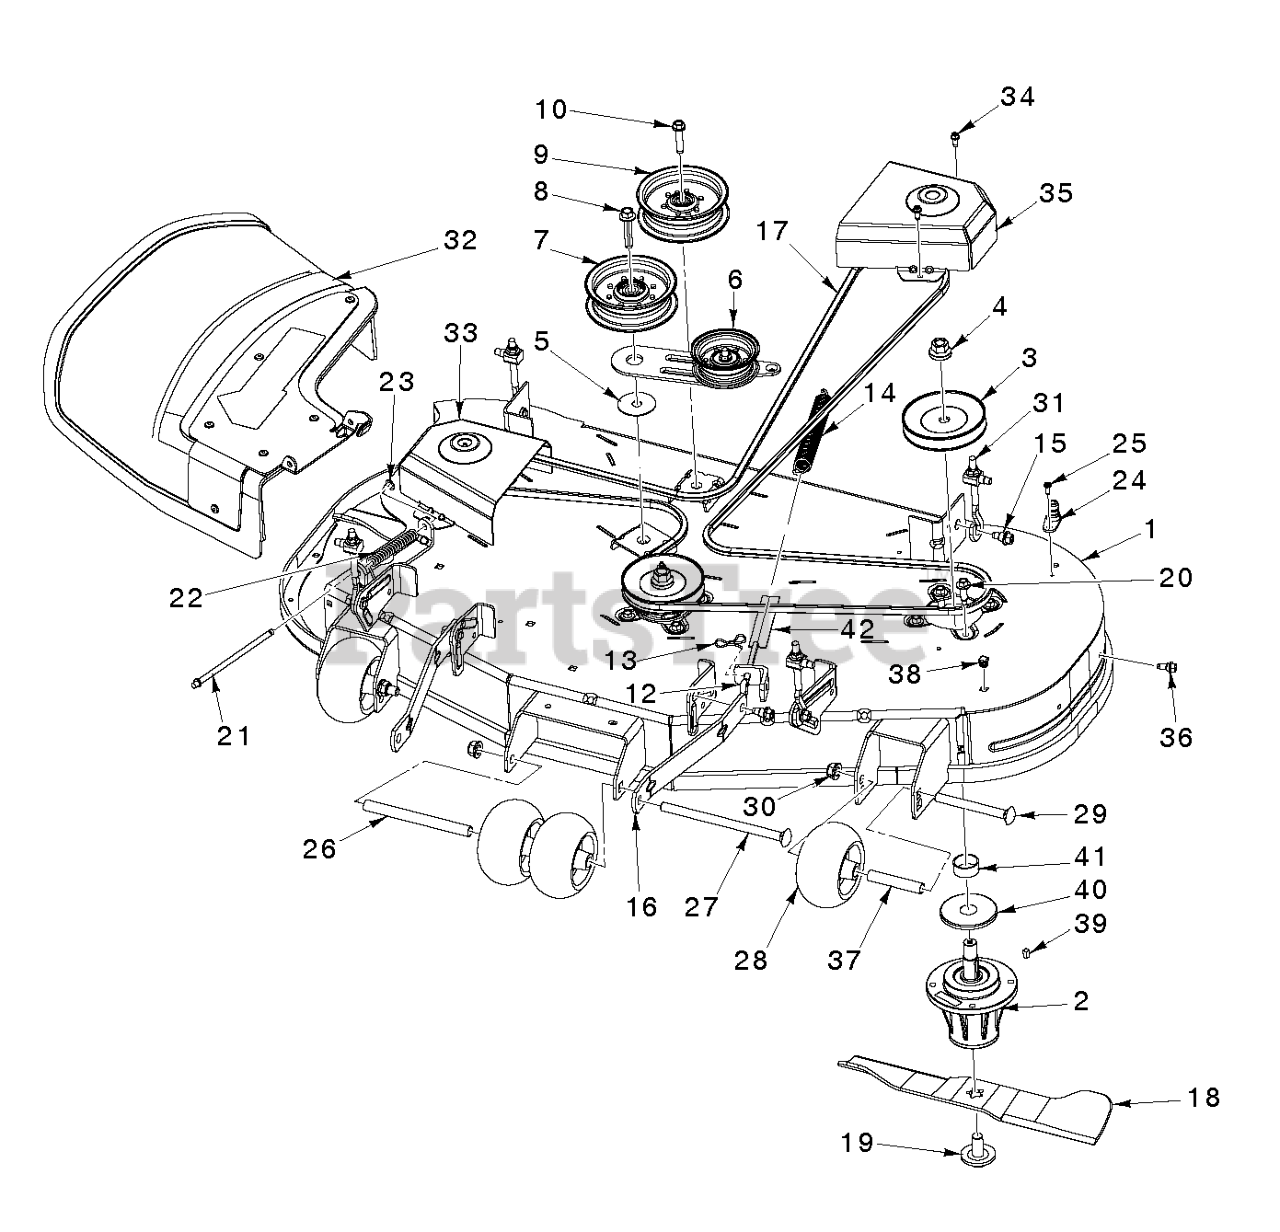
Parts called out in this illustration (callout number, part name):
1	Decals
6	ARM.PNT.CLUTCHING.ASM.EDIP
7	PULLEY.IDLER.MWR.STATI.LH
8	SCREW.7/16-14 X 2.125.WASHER
9	PULLEY.IDLER.2006
10	BOLT;HEX_3/8-16 X 1.78.CLRZINC
13	PIN.COTTER.5/16.BOW TI
14	SPRING.EXTENSION
15	BOLT.SHOULDER
16	ARM.RFIXED.MOWER.SUSPNSIONX431
18	BLADE.BAGGER.COM.CLRCT.48".BLK
19	BLADE BOLT/WASHER
20	BOLT.HEX.WASHR.HED.313-18X1.19
22	SPRING.42.FCS.DEFLECTOR
23	NUT PUSH M
24	PORT.WASHOUT
28	ROLLER, GAUGE .635 BORN
30	NUT 1/2-13 HEX FLANGE NYLOK CL
31	NUT.HEX.FLANGE.INS.BLK.3/8-16
31	LINK.ASM.ADJUSTABLE
31	NUT NUT.3/8-16.HEX.JAM.Z 3/8-1
32	GSPW Deflectors
33	COVER.PNT.MANDREL.RH.GREY
34	SCREW.1/4-20X5/8
35	COVER.PNT.MANDREL.LH.ZTR.GREY
36	BOLT.5/16HEX.WHS.HD
39	KEY 1/4 SQ X 1.0
42	VIBRATION PAD
